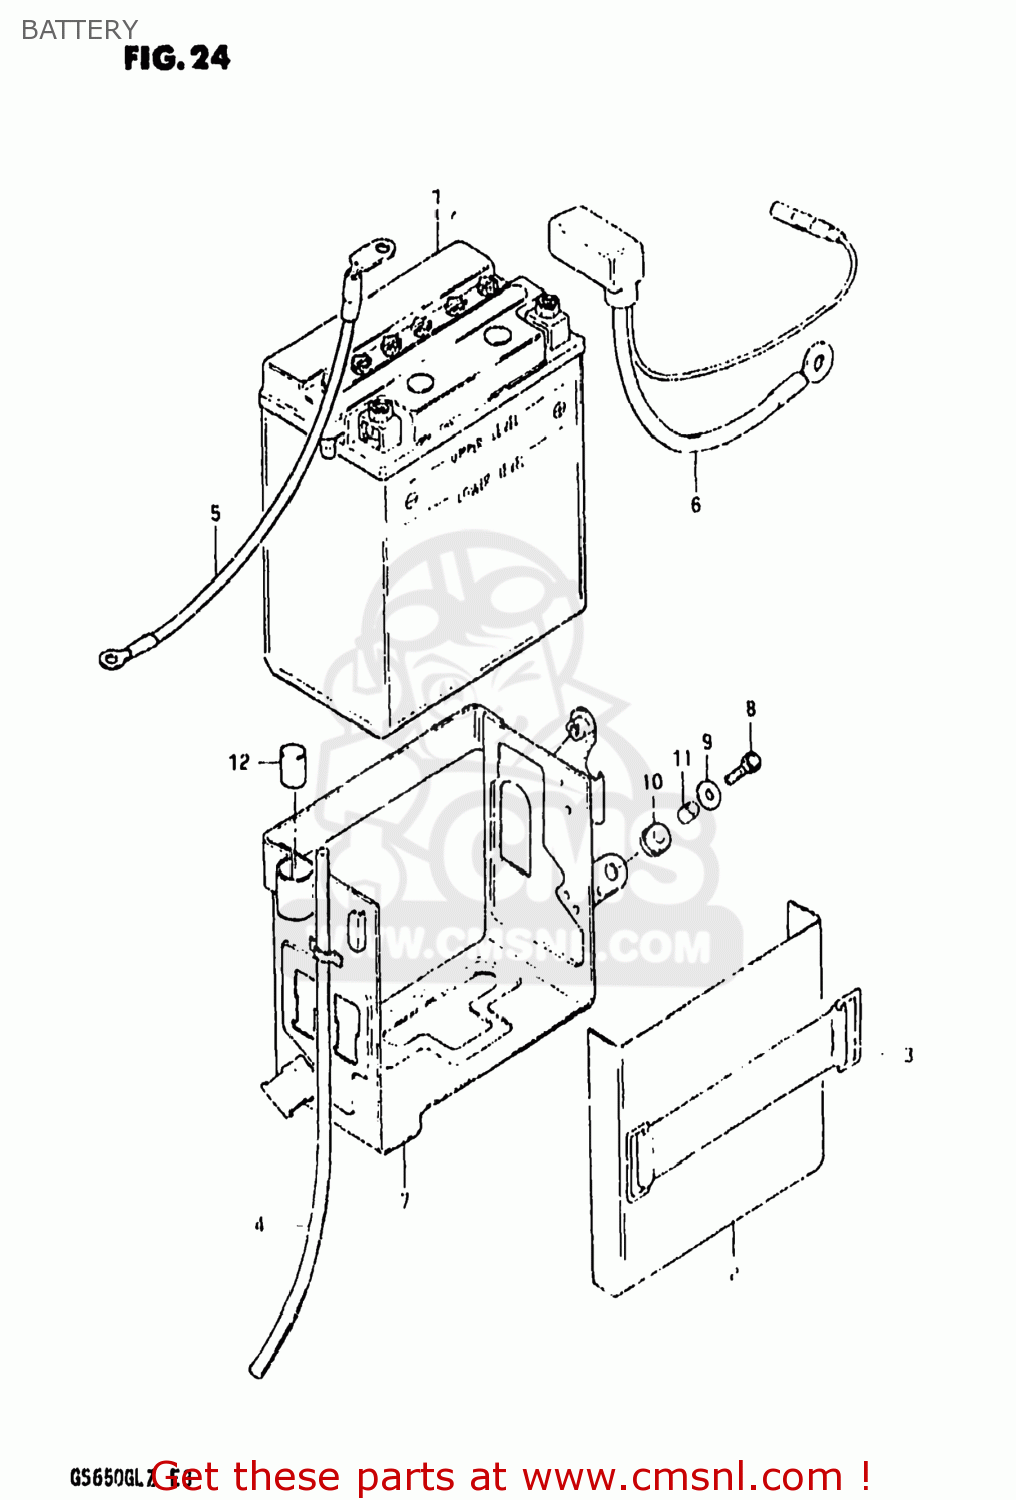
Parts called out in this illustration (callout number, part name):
1	BATTERY ASSY (12V)
2	COVER,BATTERY
3	BAND
4	HOSE,BATTERY EXHAUST
5	CORD,BATTERY MINUS
6	CORD,BATTERY PLUS
7	HOLDER,BATTERY
8	BOLT, UPPER
9	WASHER
10	CUSHION
11	SPACER(6.1X9X7.5)
12	CUSHION
